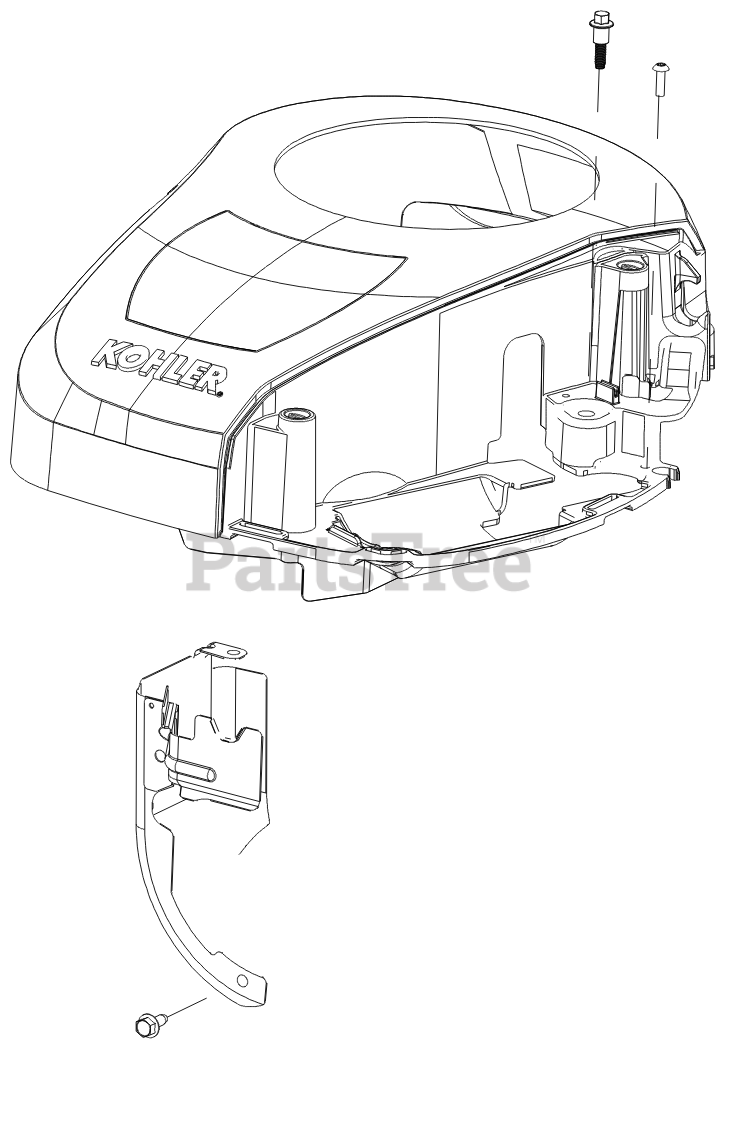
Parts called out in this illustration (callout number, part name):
1	SCREW, SHD THD FRM M6X1X26
2	KIT, BLOWER HOUSING
3	SCREW, HI-LOW
4	BAFFLE, BARREL ASSY
5	SCREW, THREAD FORMING
